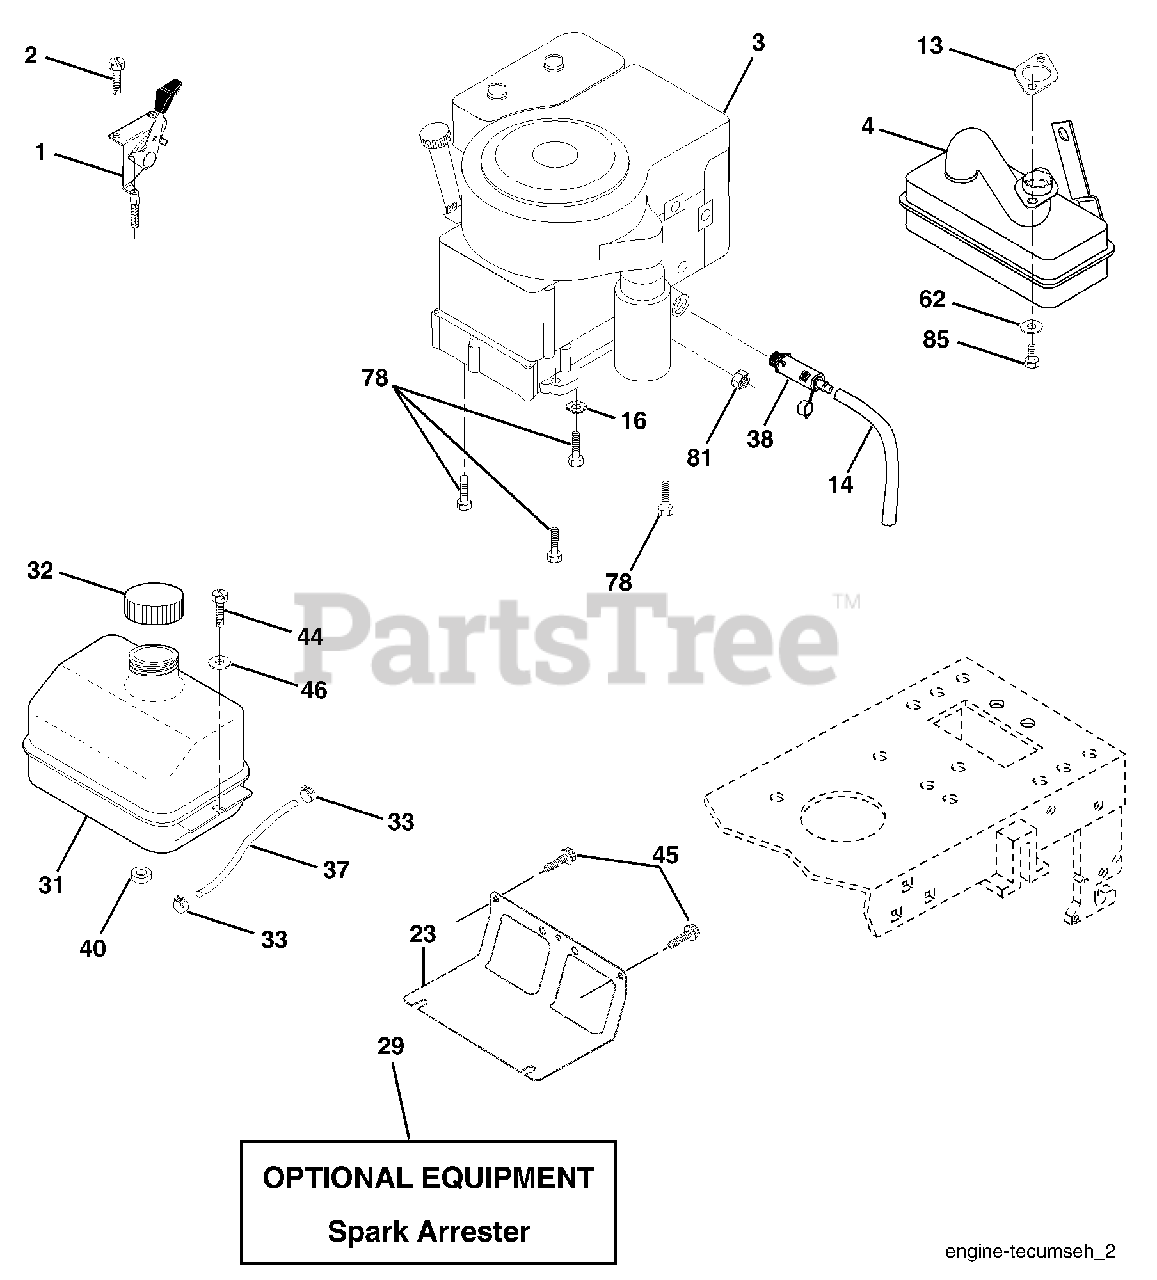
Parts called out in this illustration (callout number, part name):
1	Control Throt /Ch Flag
2	Screw Hex Thd Cut 1/4-20 x 1/2
4	Muffler
13	Gasket Muffler Tec
14	Tube Drain Oil Easy
16	Washer Lock Ext Tooth 3/8
23	Shield Browning/Debris Guard
29	Arrestor Spark
31	Tank Fuel
32	Cap Asm Fuel W/sym Vented
33	Clamp Hose Blk
37	Line Fuel 20"
38	Plug Drain Oil Easy
40	Bushing
44	Screw Hexwsh Thdrol 1/4-20 x 3/4
45	Screw Hex Wsh Thdrol 3/8-16
46	Washer 9/32 x 7/8 x 16ga
62	Washer Lock 5/16
78	Screw 3/8-16 x 1-1/4
81	Nut Keps Hex 1/4-20 Unc
85	Screw Hex Hd Cap 5/16-18 x 3/4
